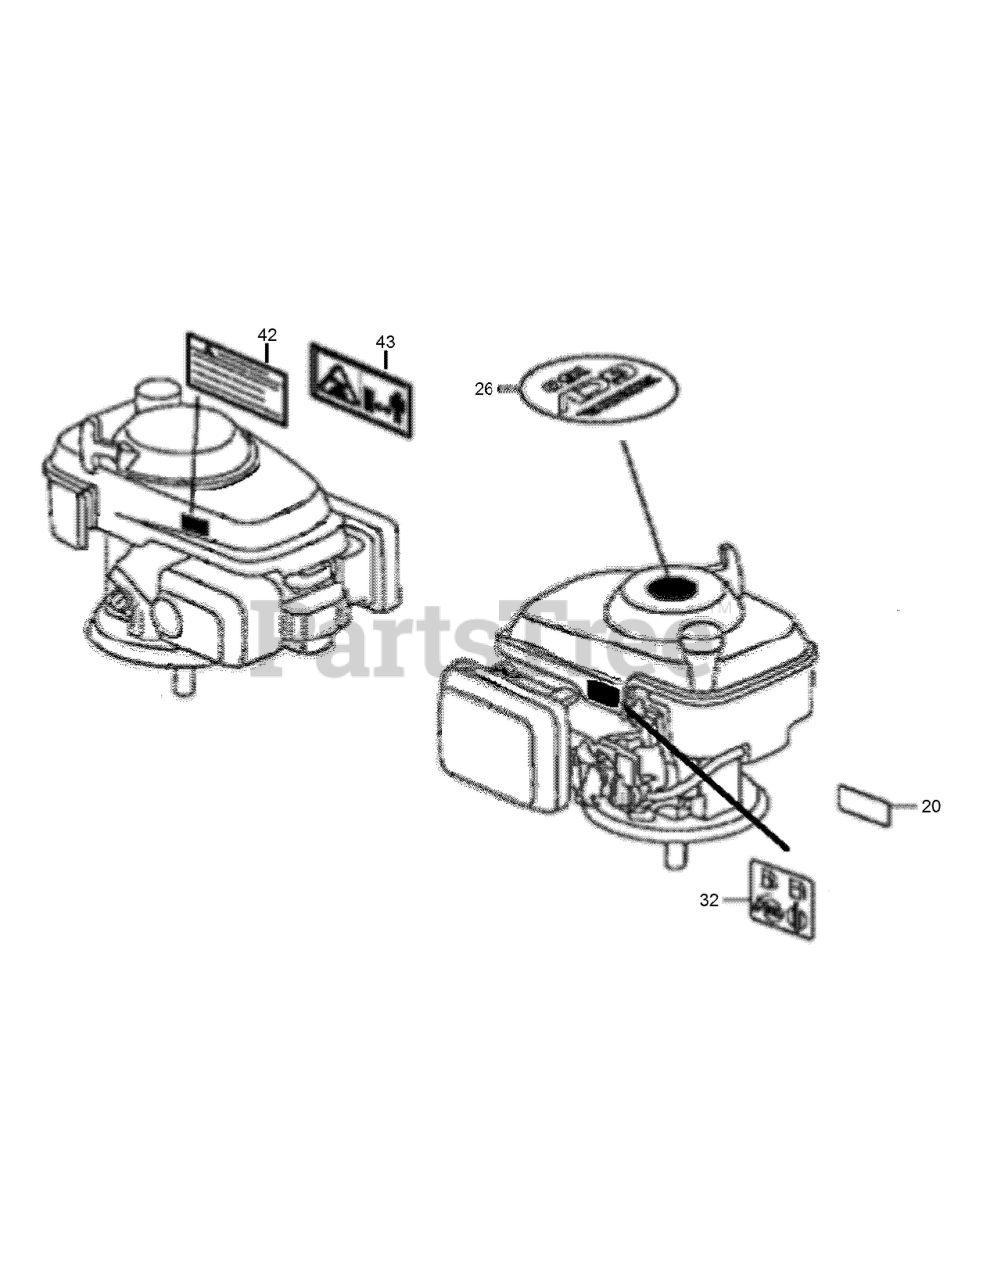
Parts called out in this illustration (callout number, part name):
20	LABEL-WARNING
26	MARK-EMBLEM
32	MARK-FUEL COCK CAUTION
42	MARK-EXHAUST CAUTION (ENGLISH)
43	MARK-EXHAUST CAUTION
